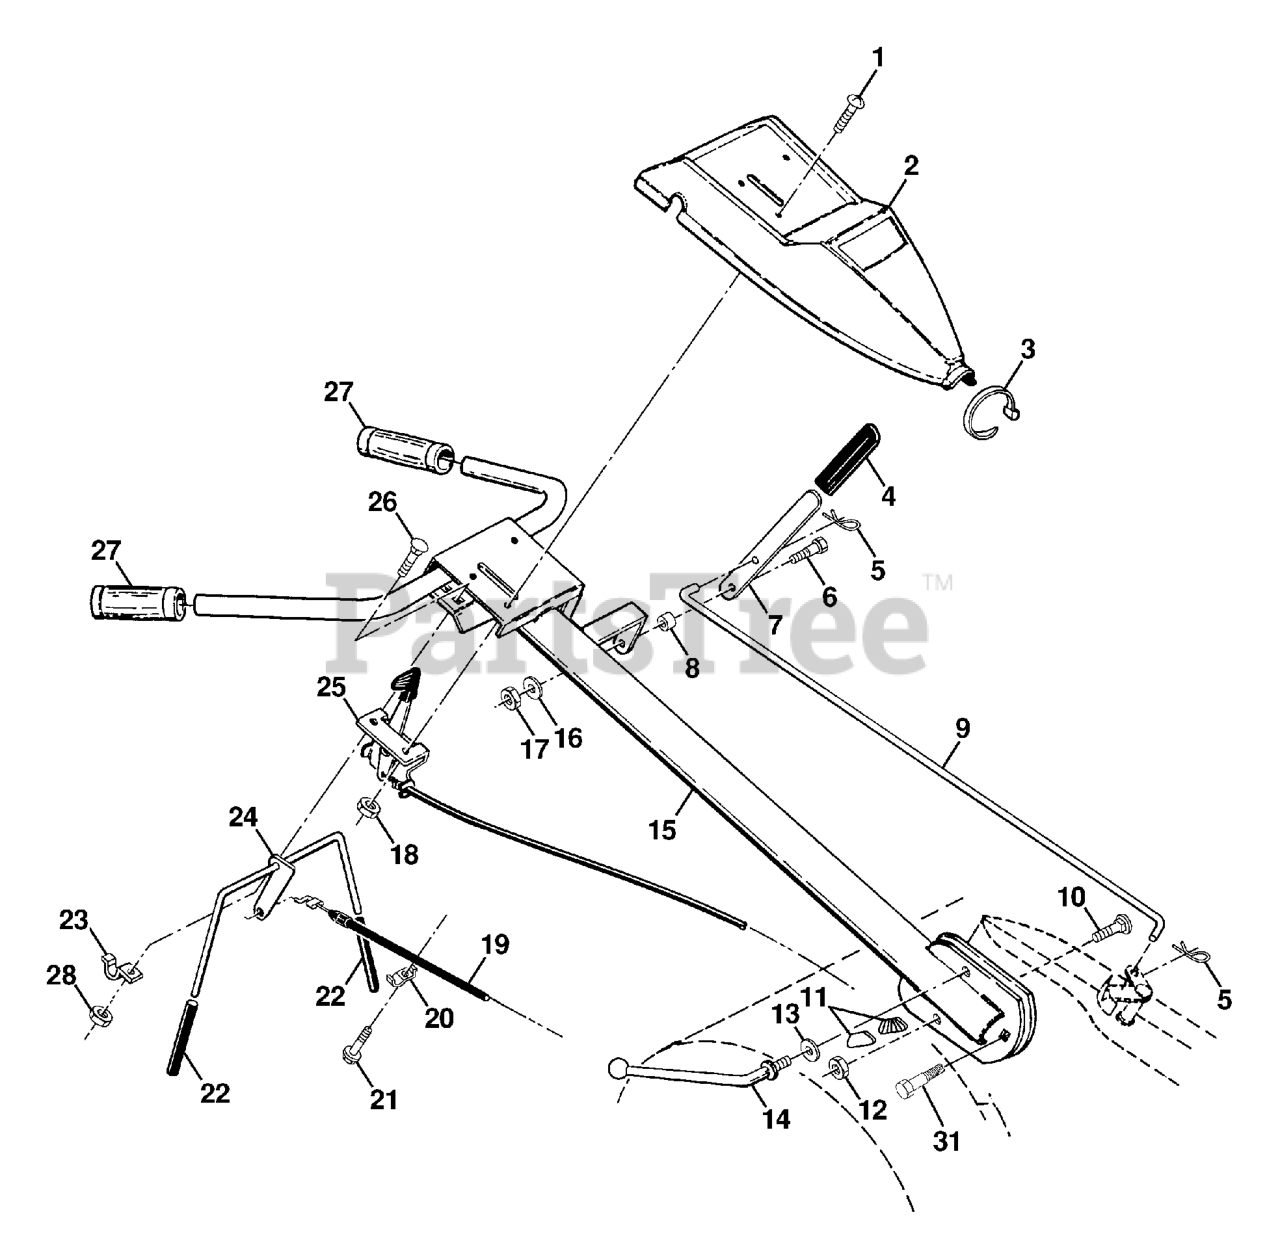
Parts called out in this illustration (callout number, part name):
1	SCREW.PNHD.10-24
3	TIE CABLE CRT
4	GRIP T
5	RETAINER M
6	SHOULDER BOLT ST
7	SHIFT HANDLE CRT
8	GROMMET.RUBBER.CRT.TILLER
9	SHIFT ROD CRT
10	BOLT D
11	LOCK.HANDLE.CRT
12	LOCKNUT
13	WASHER CRT
14	LEVER.LOCK.CRT
15	HANDLE
16	LOCKWASHER
17	NUT
18	NUT **
19	CABLE.CLUTCH
20	CONDUIT.CLIP.PLATED
21	TAPPING SCREW
22	GRIP BAR CRT(1)
23	CLAMP.BAR.CRT.BLACK
24	CONTROL BAR ASSY
25	CONT,THROTTLE
26	BOLT
27	KIT.GRIP.HANDLE.5.00.BLK.VINYL
28	NUT
31	BOLT.PIVOT
